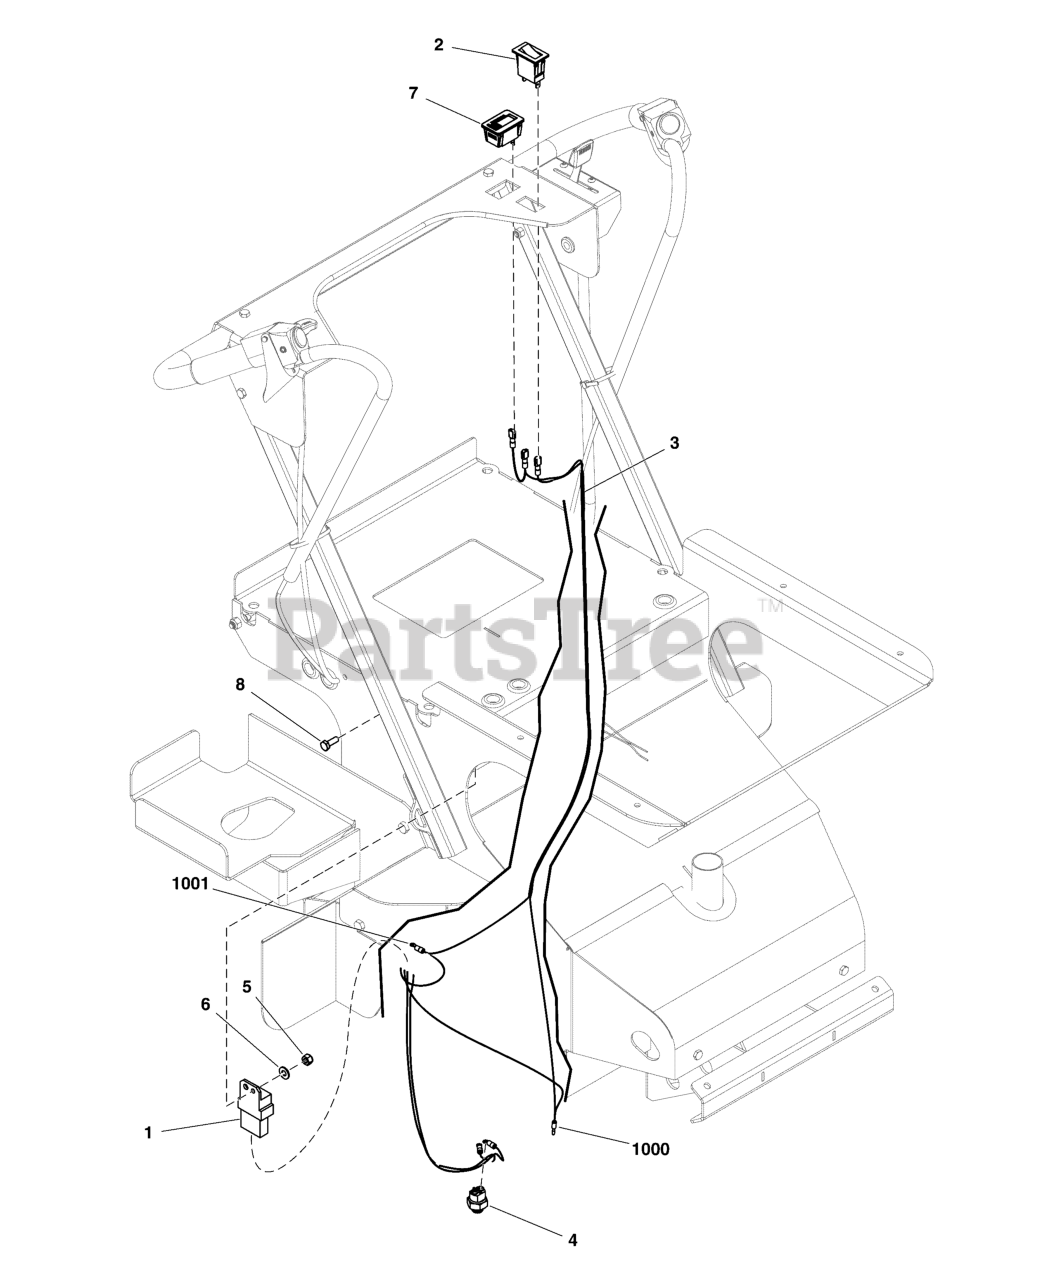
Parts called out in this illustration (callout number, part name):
1	MODULE, SAFE-START
2	SWITCH, ROCKER ON/OFF
3	HARNESS, WIRING ROVER/ROVER XC
4	PEERLESS NEUTRAL START SWITCH
5	NUT-HEX-NYLK, .250"-20 SS188
6	WSHR-STL, FLT .281" X .625" X .050" IS SS188
7	METER, TACH/HOUR INDUCTIVE PICKUP
8	SCR-CAP, HEX .250"-20 X .750" SS188
1000	Connects to Engine Ground
1001	Connects to Engine Magneto
